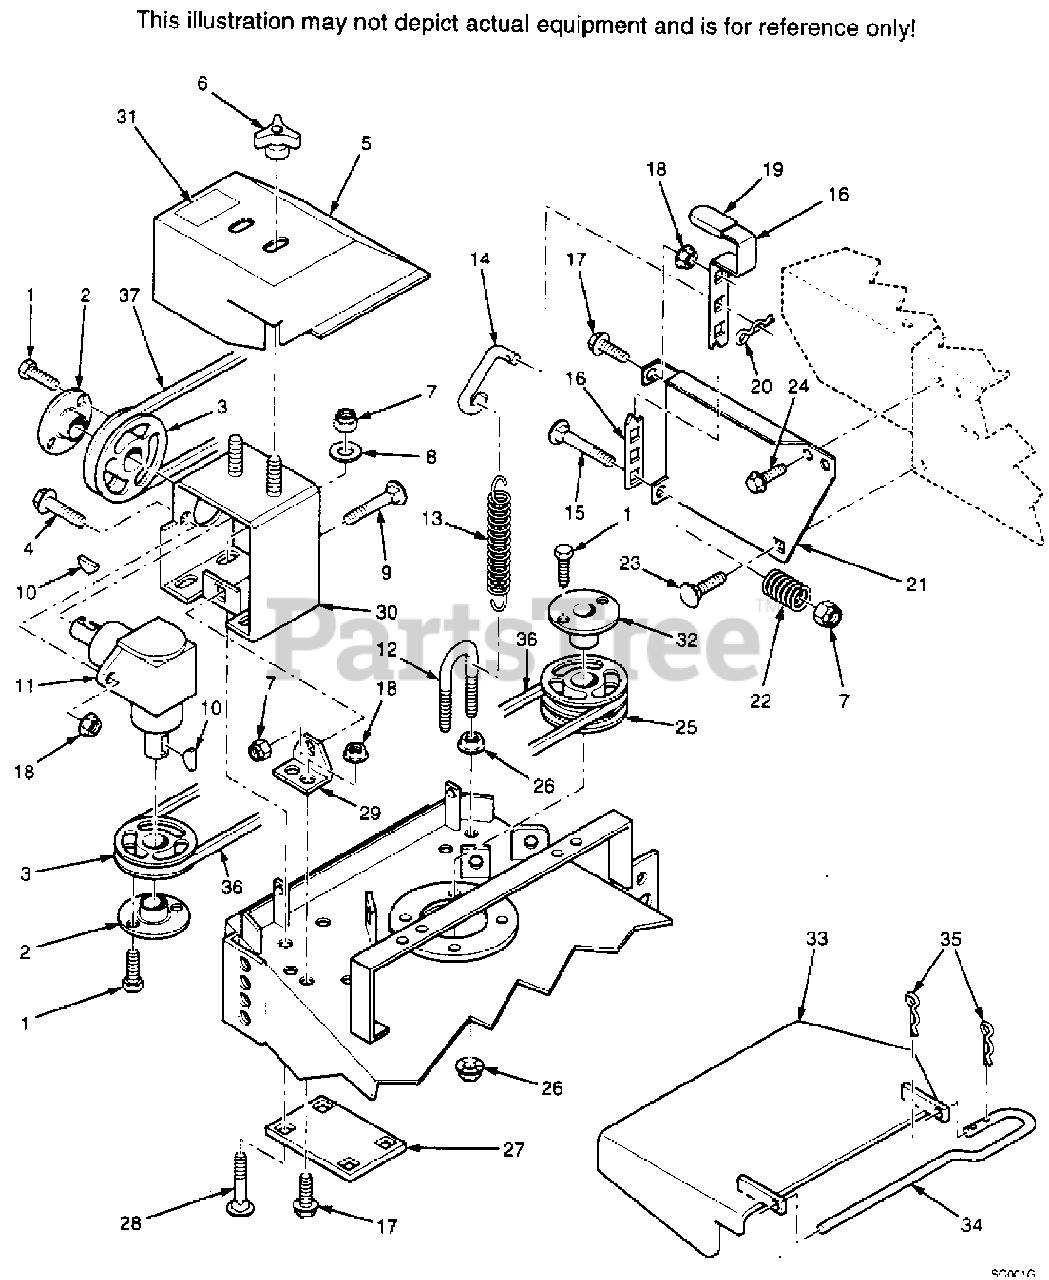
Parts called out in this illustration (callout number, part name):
1	BOLT, HEX HEAD 1/4-20 X .75
2	TAPERED HUB, .875 BORE
3	PULLEY, TAPERED BORE 5.80 O.D.
4	CAPSCREW, SERR. FLANGE 3/8-16 X 1.25
5	BELT COVER, W/DECAL
6	WINGNUT, PLASTIC 3/8-16 X .875
7	NUT, ELASTIC STOP 3/8-16
8	FLAT WASHER, 3/8(.375 X 2.00 X .060)
9	CARRIAGE BOLT, 3/8-16 X 2.00
10	KEY, WOODRUFF #9 3/16 X .75
11	GEAR BOX, 90 DEGREE DRIVE
12	U-BOLT, 5/16-18 X 2.19
13	SPRING, CLUTCH
14	ROD, COUNTER BALANCE
15	CARRIAGE BOLT
16	LEVER, COUNTER BALANCE
17	CAPSCREW, SERR. FLANGE 3/8-16 X .75
18	NUT, SERR. FLANGE 3/8-16
19	GRIP, SHIFT LEVER
20	HAIR PIN, .094 X 1.62
21	MOUNTING BRACKET, COUNTER BALANCE
22	SPRING, COMPRESSION
23	CARRIAGE BOLT, 5/16-18 X 1.00
24	CAPSCREW, 5/16-18 X .75
25	PULLEY, DOUBLE GROOVE 5.80 O.D.
26	NUT, SERR. FLANGE 5/16-18
27	REINFORCEMENT PLATE, GEAR BOX
28	CARRIAGE BOLT, 3/8-16 X 1.25
29	ANCHOR BRACKET, TENSION BOLT
30	SUPPORT WELDMENT, GEAR BOX
31	DECAL, WARNING
32	TAPERED HUB, 1.00 BORE
33	DISCHARGE CHUTE
34	ROD, DISCHARGE CHUTE
35	HAIR PIN, .080 X 1.19
36	BELT, GEAR BOX DRIVE
37	BELT, BLOWER DRIVE
